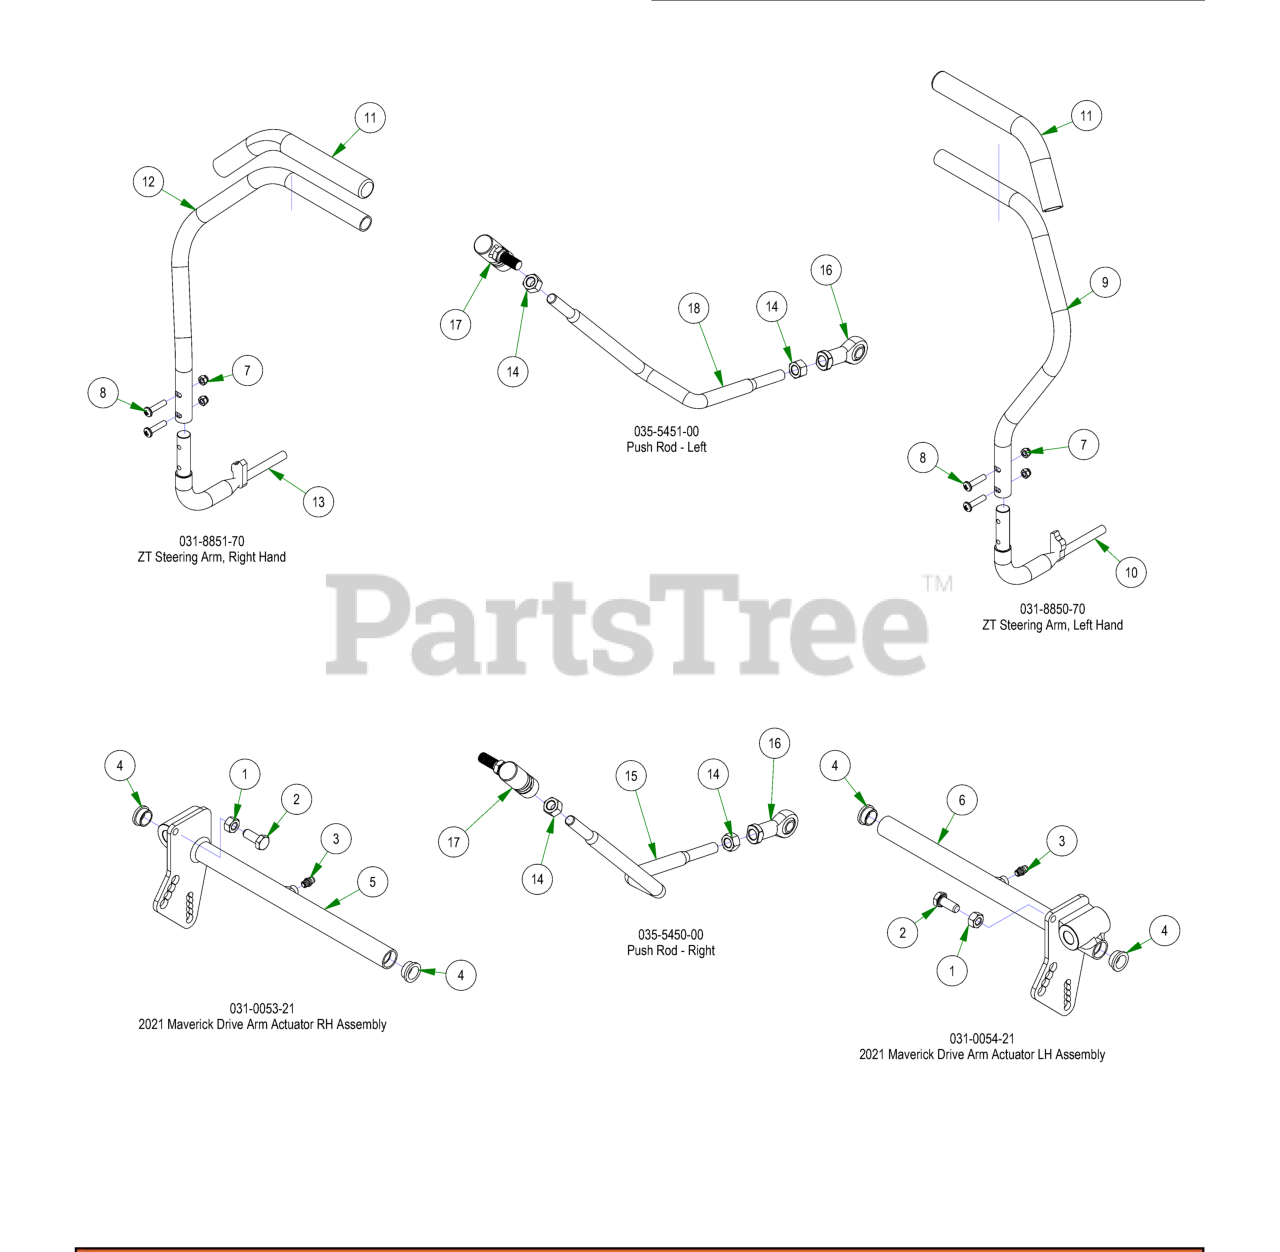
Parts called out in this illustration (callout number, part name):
1	5/16-18 HEX NUT ZINC
2	5/16-18 X 3/4 HEX CAP SCREW (GR.5) ZINC
3	1/4" Press in Grease Fitting
4	2019 Drive Arm Bushing
5	2021 Drive Actuator RH Weldment
6	2021 Drive Actuator LH Weldment
7	5/16-18 NYL INS L/N ZC
8	5/16-18 x 1 3/8" Futton Head Torx Drive Bolt
9	ZT Direction Steering Arm (Left)
10	Steering Arm Elbow (Left)
11	Rubber Grip
12	ZT Direction Steering Arm (Right)
13	Steering Arm Elbow (Right)
14	3/8" Fine Threaded Jam Nut
15	Push Rod - Right (Rod Only)
16	Spherical Rod End - Outlaw
17	Quick Release Ball Joint
18	Push Rod LH (Rod Only)
